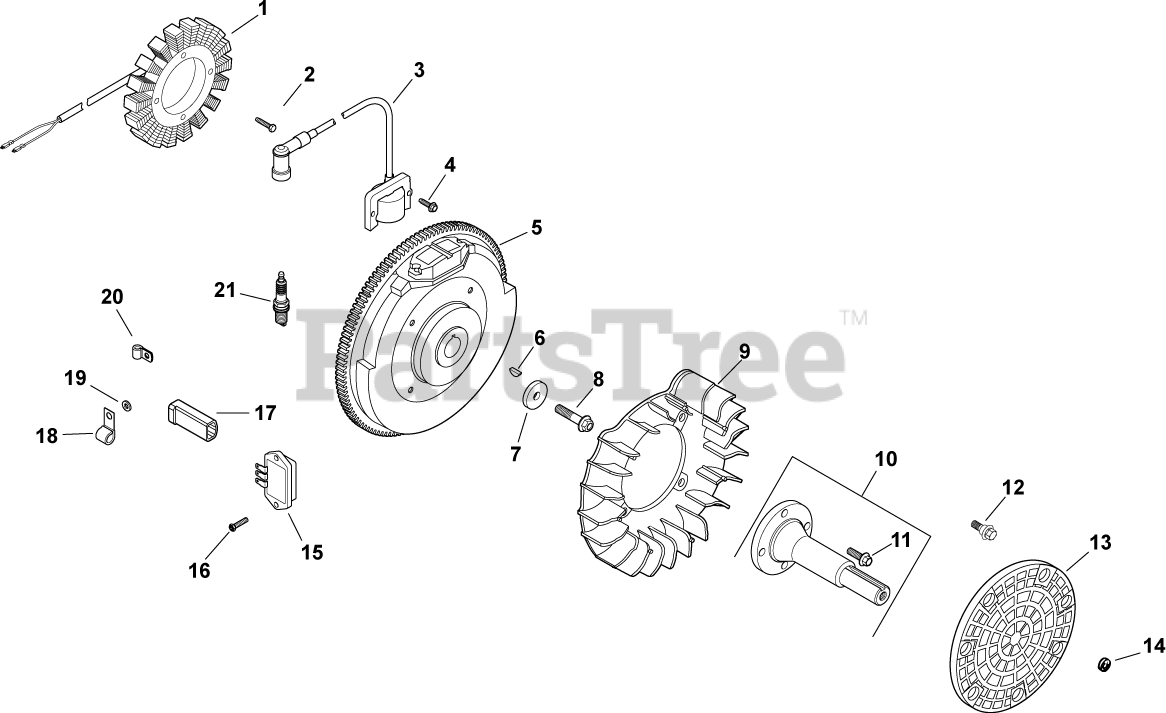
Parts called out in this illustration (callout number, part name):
1	KIT, 15 / 20 AMP STATOR
2	SCREW, M5X0.8X25 - (#25086402S)
3	KIT, MODULE IGNTN (CDI FIXED)
4	SCREW, FLG THD FRM M5X.8X20-(#25086399S)
6	KEY, 3/16" X 5/8"
7	WASHER, FLAT 13/32"
8	SCREW, FLG M10X1.5X45 - (#25086361S)
9	FAN - USE (#24 157 11-S)
10	SHAFT
11	SCREW, FLG M8X1.25X25
12	BOLT, SHOULDER
13	SCREEN, GRASS-USE 24 755 171-S
15	REG/RECT-15 AMP (KM)-USE 41 403 10-S
16	SCREW, HEX FLANGE HI-LO
17	CONNECTOR
18	CLIP, CABLE
19	WASHER, FLAT 1/4" (O.D. 1/2")
20	CLIP, TUBE & WIRING (KM)
21	PLUG, SPARK (STD)
